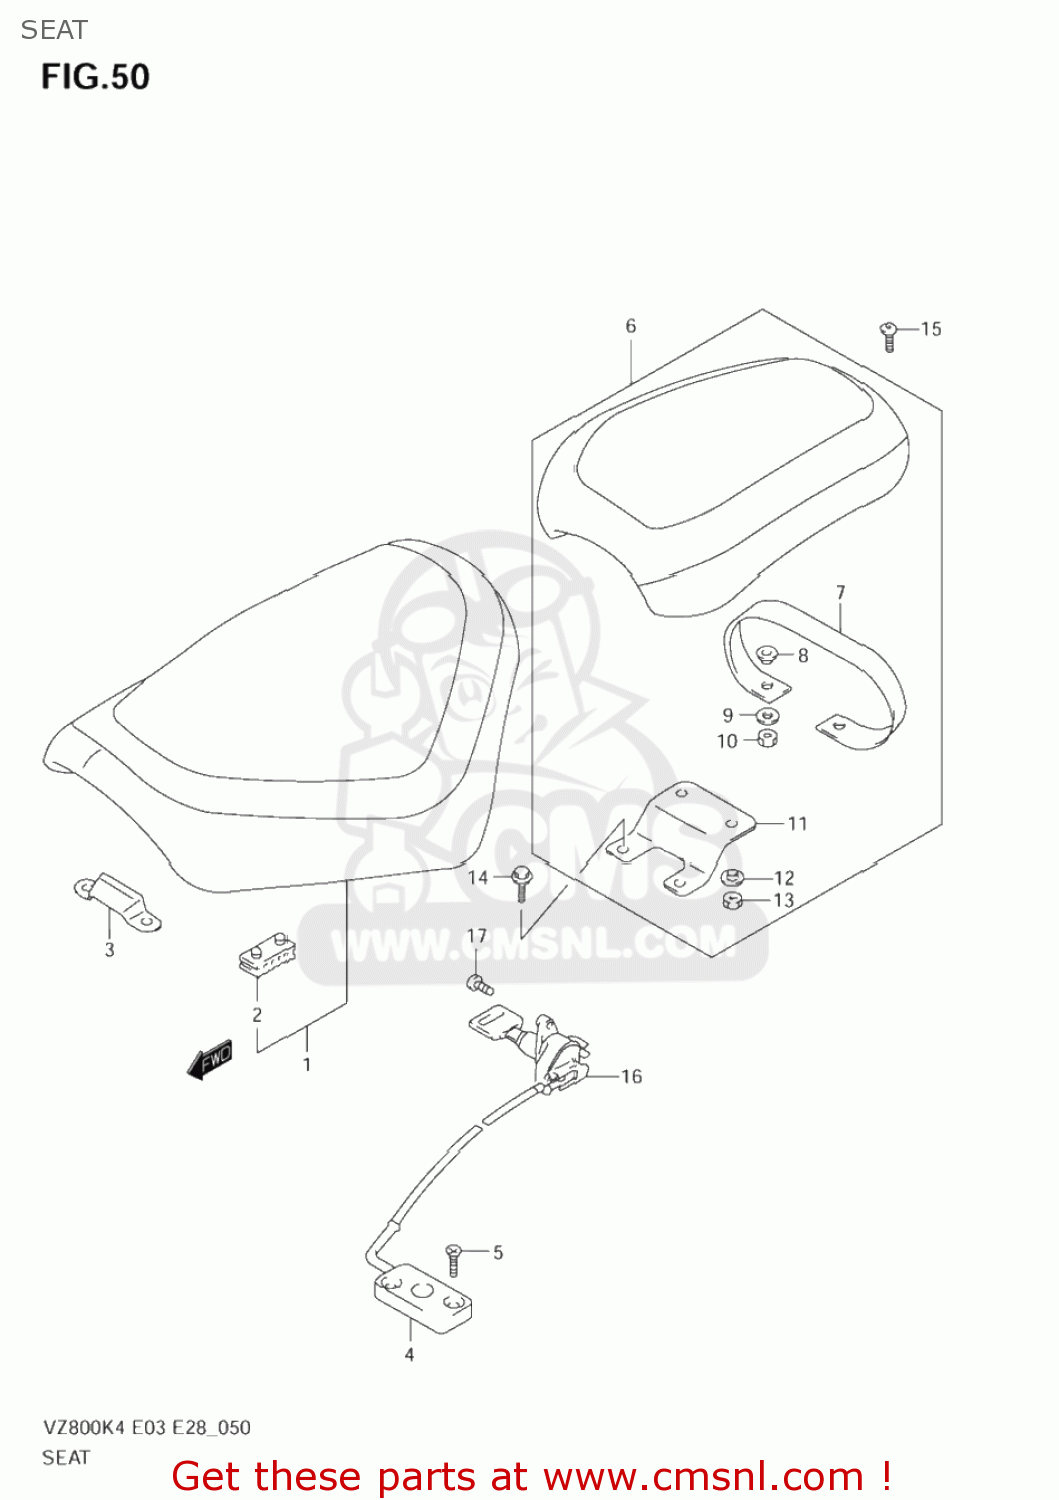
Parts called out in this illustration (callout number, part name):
1	SEAT ASSY(BLACK)
2	CUSHION,SEAT(40X20X15)
3	PLATE,FR SEAT HOOK
4	BRACKET,SEAT SUPPORT FR
5	SCREW
6	SEAT ASSY,PILLION(BLACK)
7	BAND ASSY,SEAT(BLACK)
8	WASHER
9	WASHER(6.5X18X1.6)
10	NUT
11	PLATE,PILLION SEAT
12	WASHER
13	NUT
14	BOLT
15	BOLT(8X16)
16	LOCK SET,SEAT
17	SCREW(6X14)
